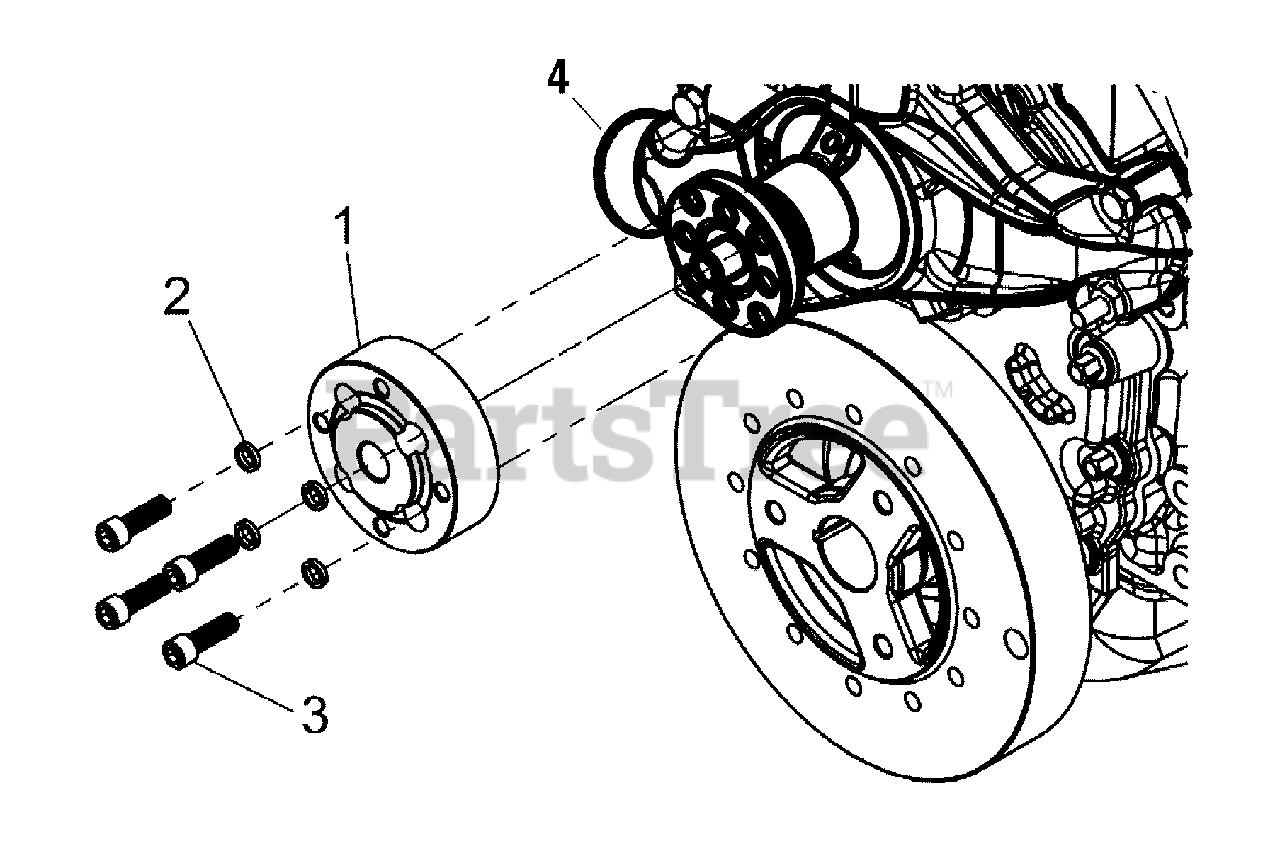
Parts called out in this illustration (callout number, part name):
1	ADAPTER
2	WASHER
3	SCREW
